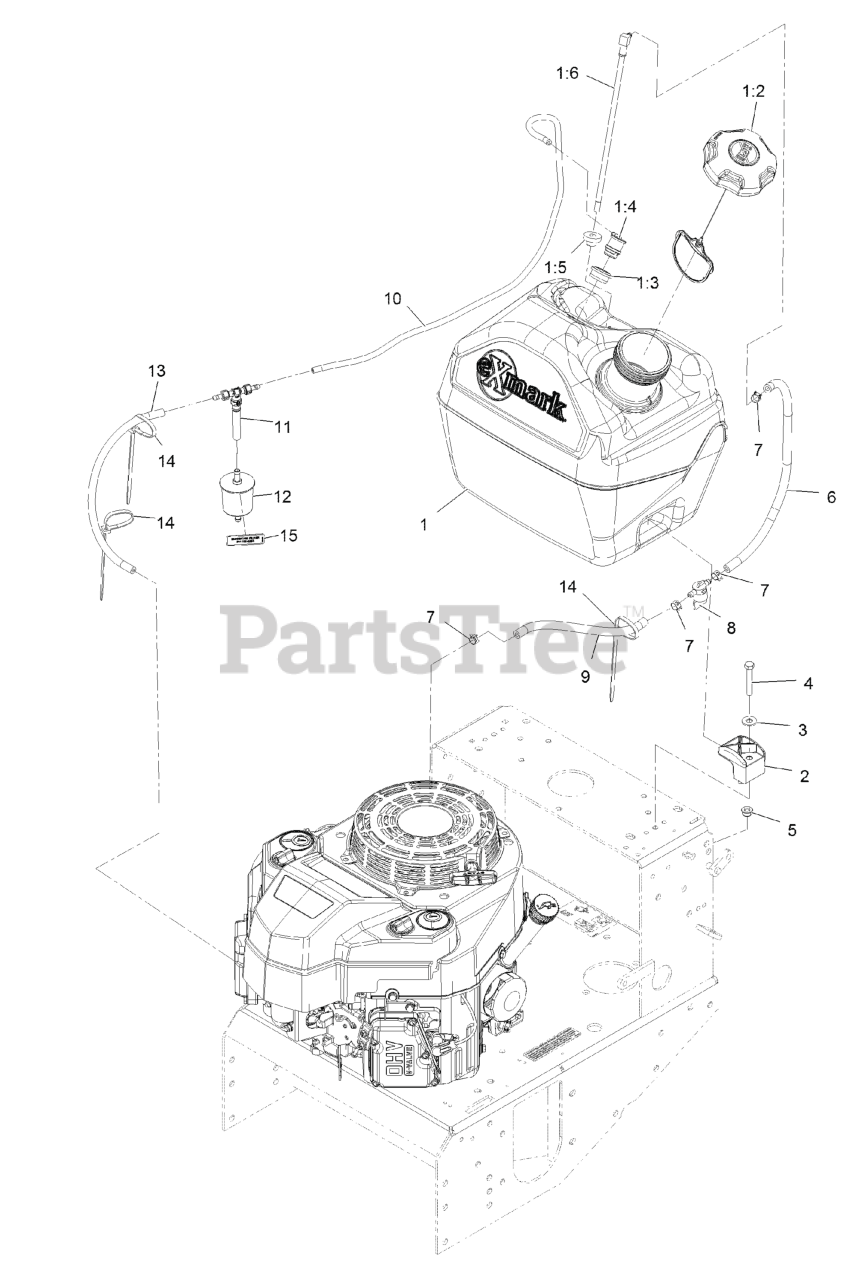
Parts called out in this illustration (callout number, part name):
1	ASM, FUEL TANK 5 GAL
1:2	CAP-FUEL, RATCHETING
1:3	GROMMET
1:4	VALVE-VENT, FUEL
1:5	BUSHING
1:6	FITTING, FUEL W/LINE AND SCREEN
3	WASHER-FLAT
4	SCREW-HH
5	NUT-HF, NI
6	HOSE-FUEL
7	CLAMP-HOSE
8	VALVE-FUEL
9	HOSE-FUEL
10	HOSE-EMISSIONS
11	TEE AND CHECK
12	FILTER-FUEL
13	HOSE-FUEL
14	TIE-PLASTIC
15	DECAL-FILTER, EMISSIONS
